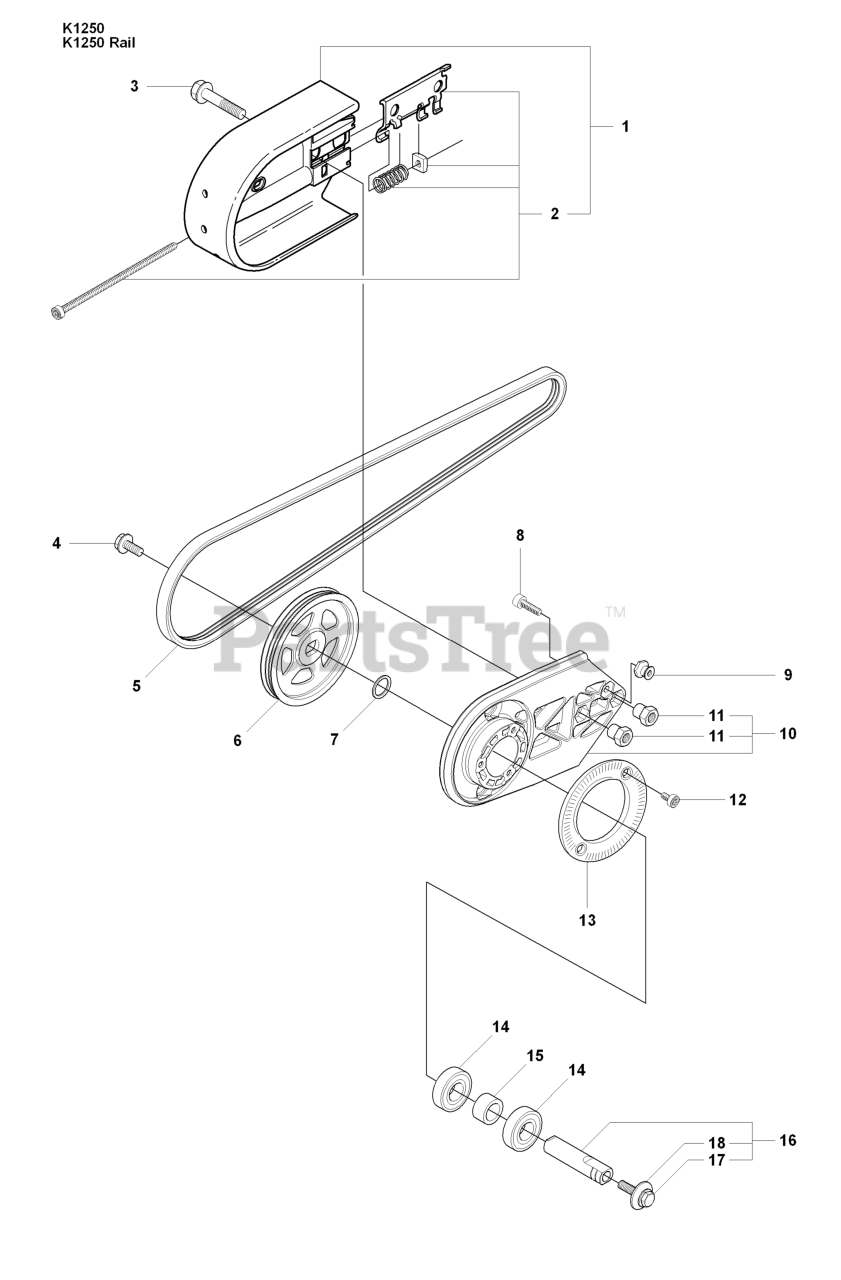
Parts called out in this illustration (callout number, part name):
1	COVER
5	BELT
6	RP PULLEY
6	%PULLEY
7	WASHER 15X21
8	SCREW MC6S 5X16
10	HOUSING
14	BALL BEARING
16	SHAFT
17	SCREW
18	WASHER
